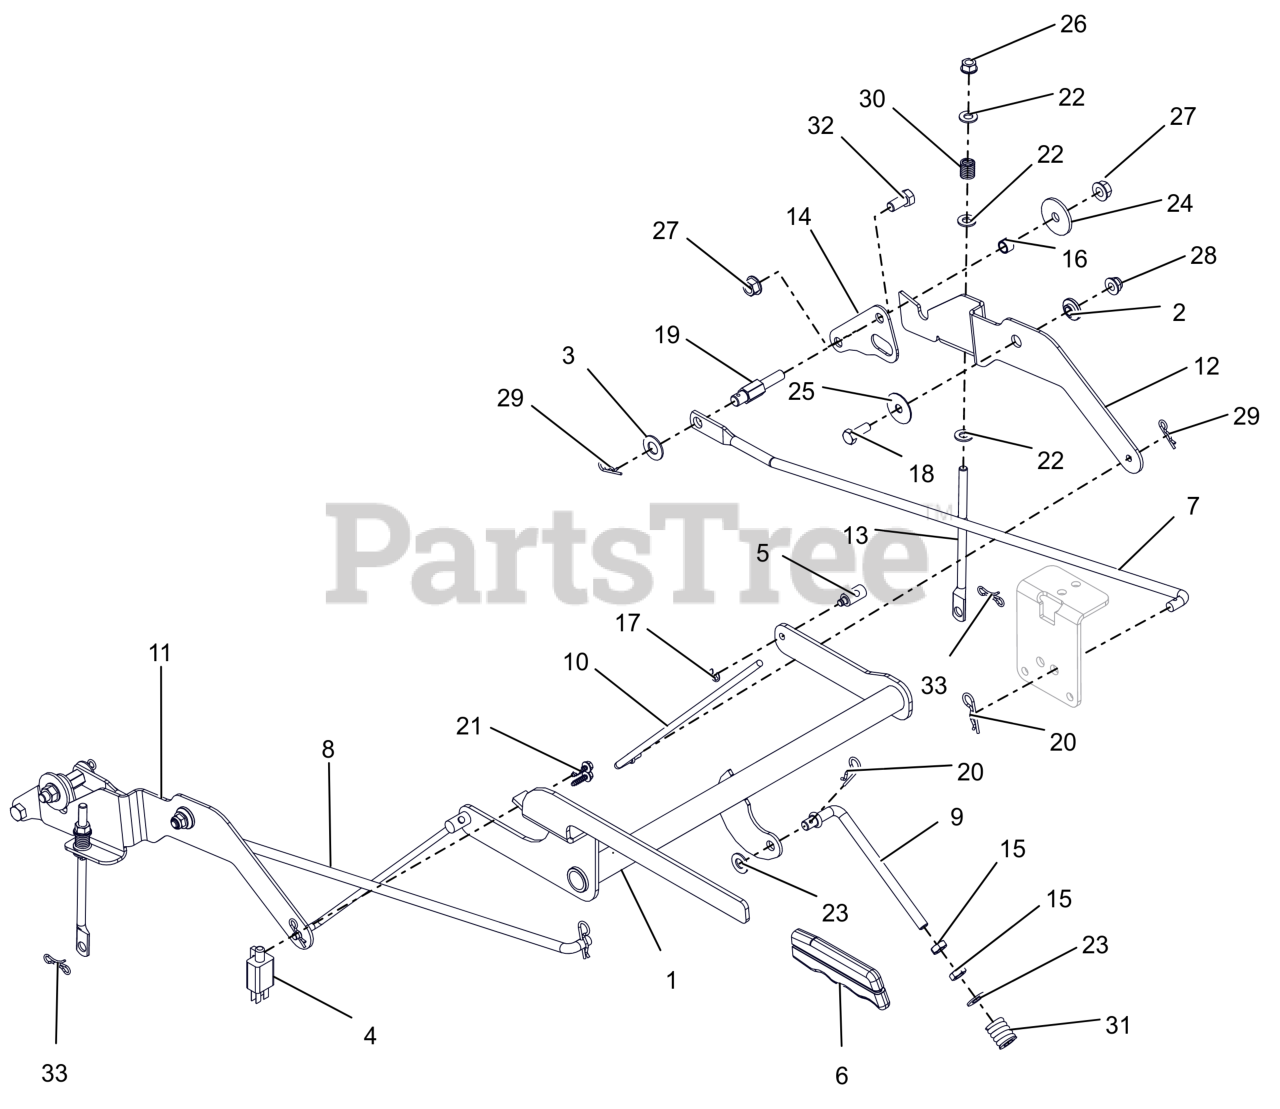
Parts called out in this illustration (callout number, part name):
1	WLDMT, BRAKE LEVER
2	BSHG, FLG .325X.499X.26X.88
3	WSHR, FLT .505X1.00X.062 ZCC
4	SWITCH- DOUBLE POLE N.O./N.O.
5	TRUNION, 1/4-20
6	GRIP, PARKING BRAKE (YELLOW)
7	LINKAGE, STEERING - LH
8	LINKAGE, STEERING - RH
9	LINK, OVER CENTER, PARKING BRK
10	LINK, BRAKE ARM
11	INTERLOCK, RH BRAKE LINK
12	INTERLOCK, LH BRAKE LINK
13	LINK, BRAKE COG
14	PLATE, TRANSAXLE ADAPTOR
15	NUT-JAM .375-16 G2 ZCC
16	SPCR, SLV .385X.500X.350
17	RG-RTNG-EXT .250X.025
18	BLT, HEX .31-18X.875 G5 ZCC
19	POST, STEERING LINK MOUNTING
20	PIN, HAIR #203 .09X1.50 ZCC
21	SCR, PLASTITE #12X.75 ZCC
22	WSHR,FLT .344X.688X.065 ZCC
23	WSHR,FLT .406X.812X.065 ZCC
24	WSHR, FLT .380X1.50X.125 ZCC
25	WSHR, FLT .347X1.254X.048 ZCC
26	NUT,LK-CTR-FLG .31-18 GF ZCC
27	NUT-LK-CTR-FLG .375-16 GF ZCC
28	NUT,LK-NYL-FLG .31-18 G5ZC120
29	PIN, HAIR #213 .08X1.19 ZCC
30	SPRING, COMPRESSION
31	SG-COMP .187X.56X1.62
32	BLT,HEX .38-16X.75 G5 ZCC
33	PIN, BOWTIE #72 ZCC
